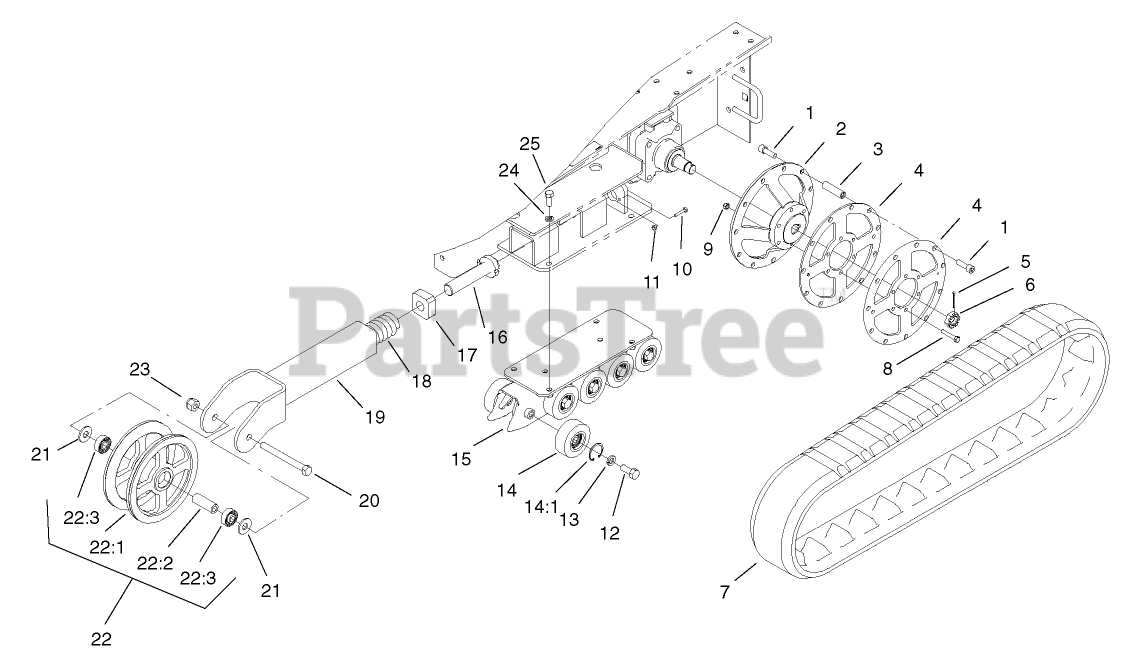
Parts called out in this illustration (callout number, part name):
1	SCREW-HSH
2	DRIVE WHEEL ASM
3	SPACER-WHEEL, DRIVE
4	PLATE-WHEEL, DRIVE
5	PIN-COTTER
7	TRACK
8	SCREW-HH
9	NUT-LOCK, SIDE
10	SCREW-HH
11	NUT-LOCK, NI
12	SCREW-HH
13	WASHER-LOCK
14	BOGGY WHEEL ASM
14:1	RING-RETAINING
15	TRACK GUIDE ASM
16	BOLT-TENSIONER
17	BLOCK-TENSIONER
18	SPRING-COMPRESSION
19	TENSIONER ARM ASM
20	SCREW-HH
21	WASHER-FLAT
22	TENSIONER WHEEL ASM
22:1	TENSIONER WHEEL ASM
22:2	SPACER-WHEEL, TENSIONER
22:3	BEARING
23	NUT-HEX
24	WASHER-LOCK
25	SCREW-HH
